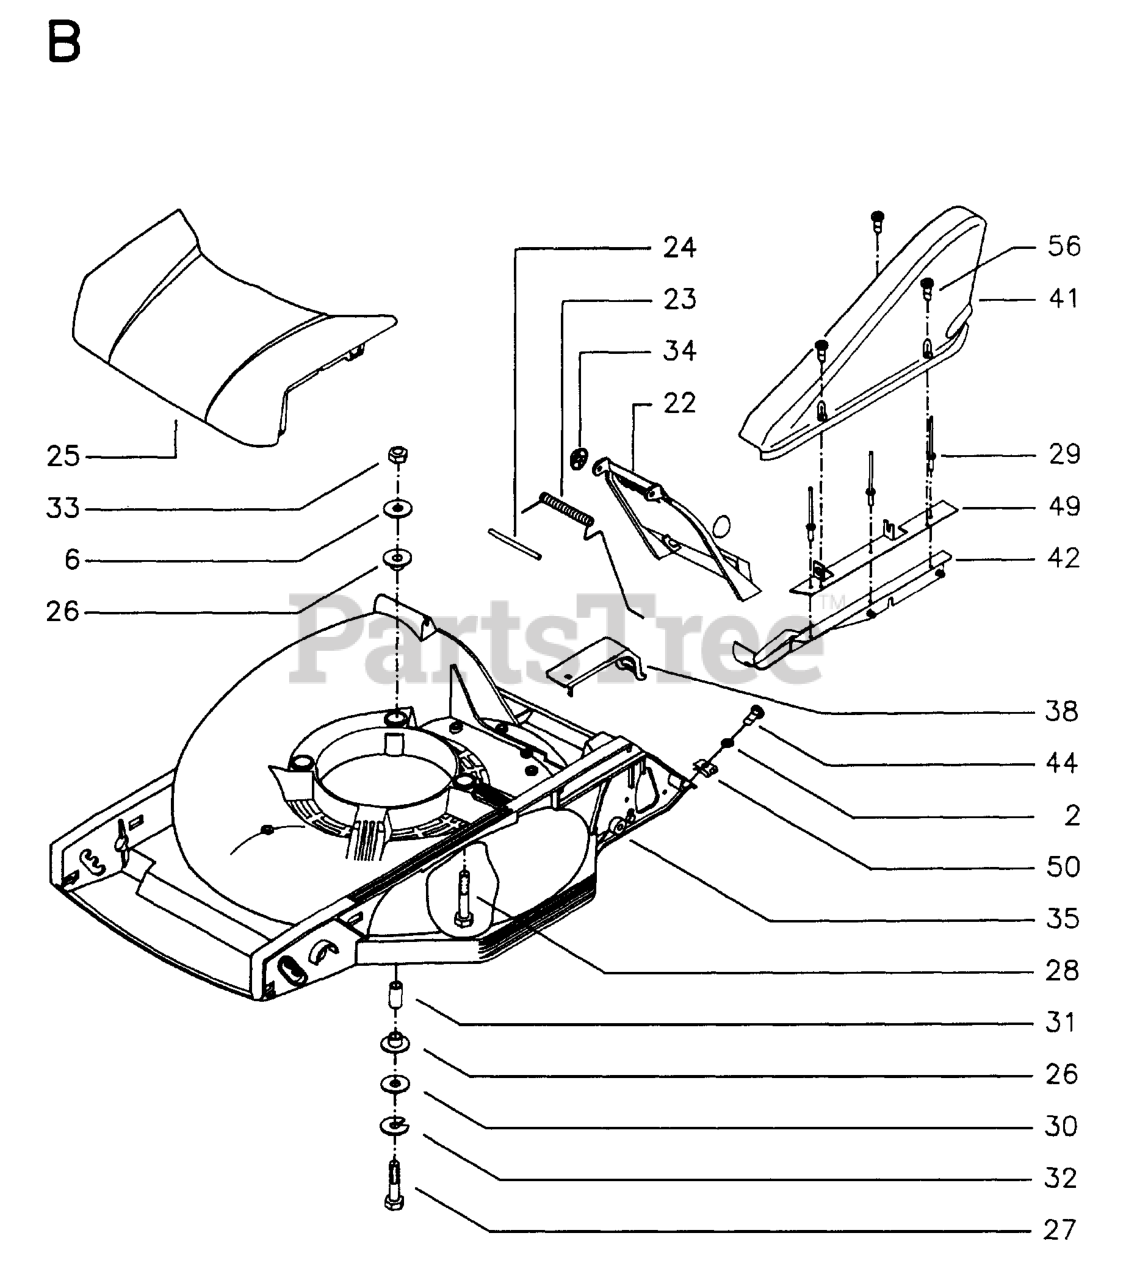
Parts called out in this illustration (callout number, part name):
24	PIN
32	SPRING WASHER
33	LOCKNUT M8
50	LOCK PLATE
